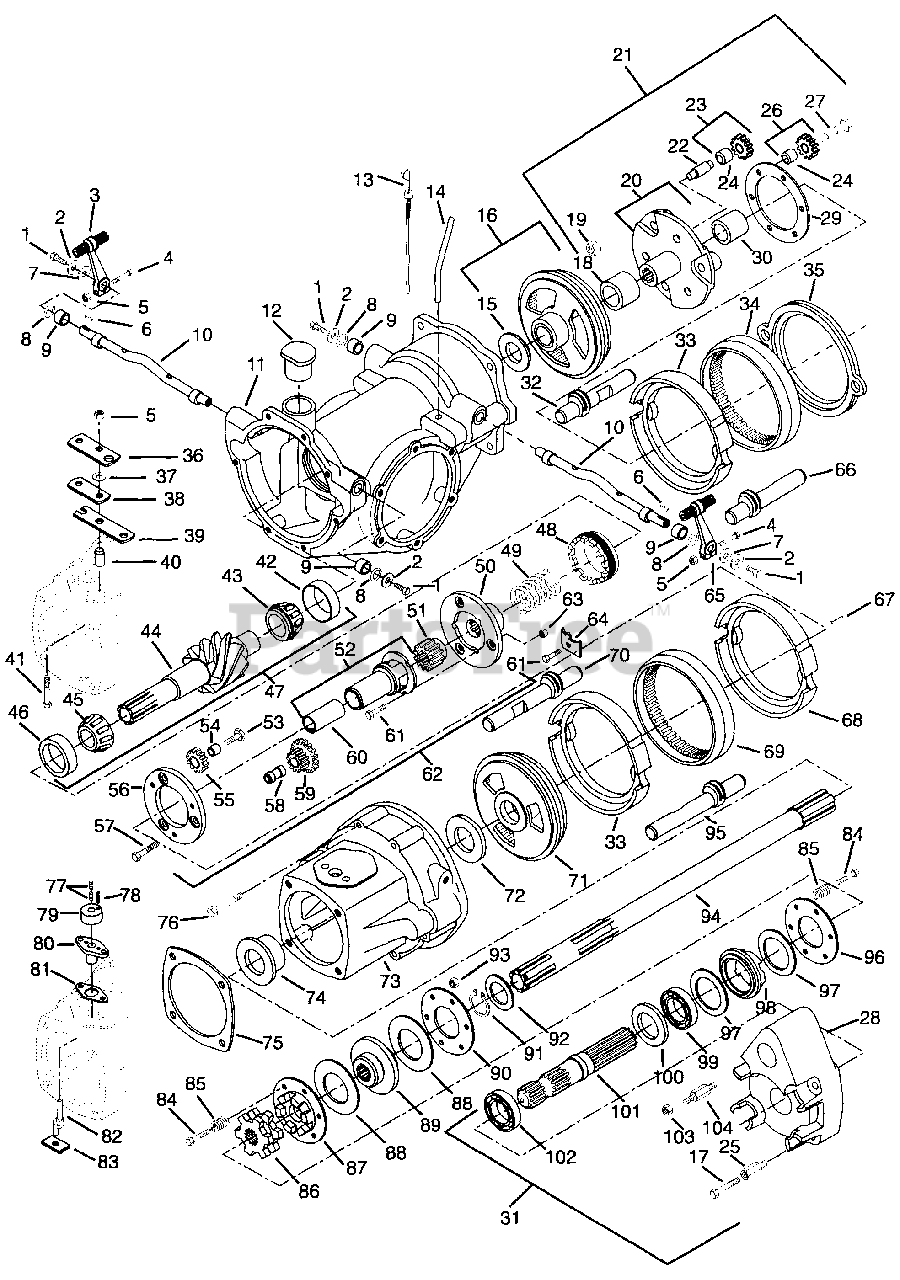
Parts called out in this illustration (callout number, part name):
1	Bolt-Hex .25-20 x .50 Grade 5
2	Washer-Flat-Steel .281 x 1.250 x .048
3	Assembly, Forward Reverse Lever
4	Bolt-Hex .31-18 x 2.00 Grade 5
5	Nut-Locking-Center .312-18 Grade 2
6	Key-Woodruff .13 x .63
7	Washer-Flat .812 x 1.500 x .139
8	O-Ring .750 x 1.0
9	Bushing, Sleeve .749 x 1.00 x .625
10	Shaft, Actuating
11	Transmission Housing
12	Plug, Oil Filler
13	Assembly, Dip Stick
14	Guide, Dip Stick
15	Plate, Rear Thrust
16	Assembly, Ring Gear & Bushing
17	Bolt-Hex .50-13 x 1 Grade 5
18	Bushing-Sleeve 1.125 x 1.502 x 1.312
19	Nut-Locking .312-18 x .265
20	Assembly, Planet Gear Carrier
21	Assembly, Hi-Lo Planetary
22	Pin, Hi-Lo Orbit Gear
23	Assembly, Internal Orbit Gear
24	Bushing-Sleeve .500 x .627 x .465
25	Stud, Quick Hitch
26	Assembly, External Orbit Gear
27	Bolt, Orbit Gear
28	Casting, Quick Hitch
29	Spacer, Pin
30	Bushing-Sleeve .737 x .877 x .683
31	Quick Hitch Assembly
32	Rod, Rear Right Hand Clutch Slide
33	Assembly, Clutch Cup
34	Gear, Rear Ring
35	Spacer, Rear
36	Bracket, PTO Switch
37	Washer-Flat-Steel .344 x .688 x .065
38	Spacer, Strap
39	Arm, Shifter
40	Bushing, Flange .344 x .562 x .866
41	Bolt-Hex .31-18 x 2.50 Grade 5
42	Bearing-Cup 2.328 x .465
43	Bearing-Cone 1.25 x .66
44	Weldment, 6-Lead Worm
44	Weldment, 8-Lead Worm
45	Bearing-Cone 1.250 x 2.875
46	Bearing-Cup 2.875 x .688
47	Weldment Worm Shaft Assembly 6 Lead
47	Weldment Worm Shaft Assembly 8 Lead
48	Nut-Bearing 3.00 - 16
49	Spring-Compression .188 x 1.66 x 2.0
50	Plate, Front Pin
51	Gear, Sun Pinion Spur
52	Assembly, Quill and Bushing
53	Bolt .38-24 x .860
54	Spacer .375 x .686 x .516
55	Gear, Reverse Idler Spur
56	Spacer, Front Pin
57	Bolt-Spacer .38-16 x 1.81
58	Pin, Forward Reverse Orbit Gear Steel
59	Gear, Orbit Spur
60	Bushing-Sleeve .875 x 1.002 x 2.015
61	Bolt-Hex .25-20 x .63
62	Assembly, Forward Reverse Planetary
63	Nut-Hex .250-20 Grade 2
64	Nut, Adjusting
65	Assembly, Hi-Lo Lever
66	Rod, Rear Left Hand Clutch Slide
67	Pin-Roll .368 x .500
68	Cup, Gear
69	Spur Gear
70	Rod, Left Hand Clutch Slide
71	Cone, Reverse Gear
72	Disk, Friction
73	Assembly, Advance Casting
74	Bushing-Flange 1.375 x 1.628 x .957 x 2.125
75	Gasket, Attachment
76	Bolt-Hex .31-18 x 3.25 Grade 8
77	Screw-Set .38-16 x .25
78	Pin-Roll .250 x .75
79	Body, Shipper Shaft
80	Shaft, Shipper
80	Guard, Shipper Shaft
81	Gasket, Shipper Shaft
82	Shaft, Shipper
83	Block, Trunion
84	Bolt-Hex .31-24 x 1.75
85	Spring-Compression .156 x .343 x .75
86	Dog
87	Plate, Dog
88	Washer, Friction
89	Plate, Drive
90	Plate, Back
91	Ring-Retaining-External .875 x .042
92	Washer-Thrust .877 x 1.427 x .032
93	Nut-Jam .312-24
94	Shaft, Pinion
95	Rod, Right Hand Clutch Slide
96	Plate, Back
97	Disc, Brake
98	Brake, Dog Plate
99	Bearing-Ball .984 x 2.047 x .591
100	Seal 1.102 x 2.047 x .315
101	Shaft, Quick Hitch
102	Bearing-Ball .984 x 2.04 x .59
103	Nut .50-13
104	Stud, Quick Hitch
